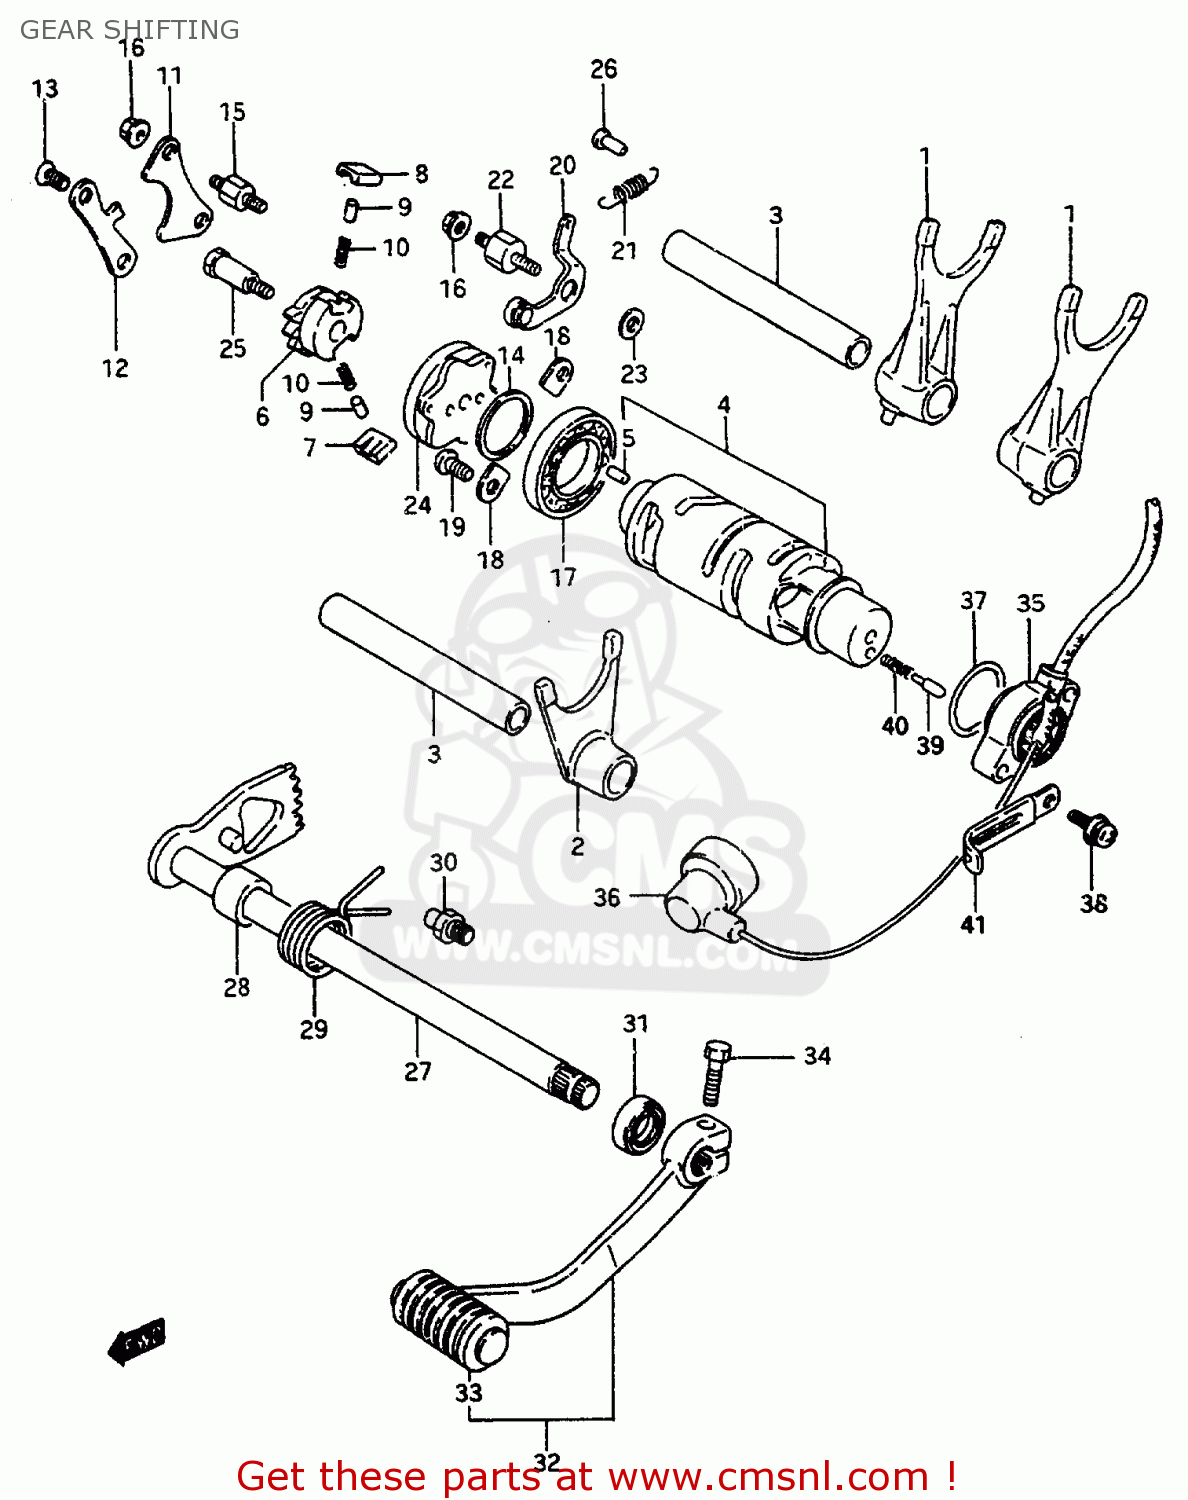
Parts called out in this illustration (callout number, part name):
1	FORK,GEAR SHIFT NO.1
2	FORK,GEAR SHIFT NO.2
3	SHAFT,GEAR SHIFT FORK(L:115)
4	CAM,GEAR SHIFT
5	PIN
6	GEAR,GEARSHIFT CAM DRIVE
7	PAWL,GEAR SHIFT NO.1
8	PAWL,GEAR SHIFT NO.2
9	PIN(5X8)
10	SPRING
11	LIFTER,GEAR SHIFT POLE
12	GUIDE,GEAR SHIFT CAM
13	SCREW
14	WASHER(25X32X3)
15	BOSS,SHIFT PAWL LIFTER
16	NUT
17	BEARING(25X47X8)
18	RETAINER
19	SCREW
20	STOPPER,GEAR SHIFT CAM
21	SPRING
22	SUPPORT,CAM STOPPER ARM
23	WASHER
24	PLATE,GEAR SHIFT CAM
25	PIN,SHIFT CAM DRIVEN GEAR
26	RIVET
27	SHAFT,GEAR SHIFT
28	SPACER(12X20X15.3)
29	SPRING
30	STOPPER,GEAR SHIFT CAM
31	OIL SEAL
32	LEVER ASSY,GEAR SHIFT
33	RUBBER,GEAR SHIFT PEDAL
34	BOLT
35	BASE,NEUTRAL SWH TERMINAL
36	CAP,OIL PRESSURE SWITCH
37	O RING(D:2.4,ID:26.2)
38	SCREW
39	PIN(5X15.5)
40	SPRING
41	CLAMP(L:65)
